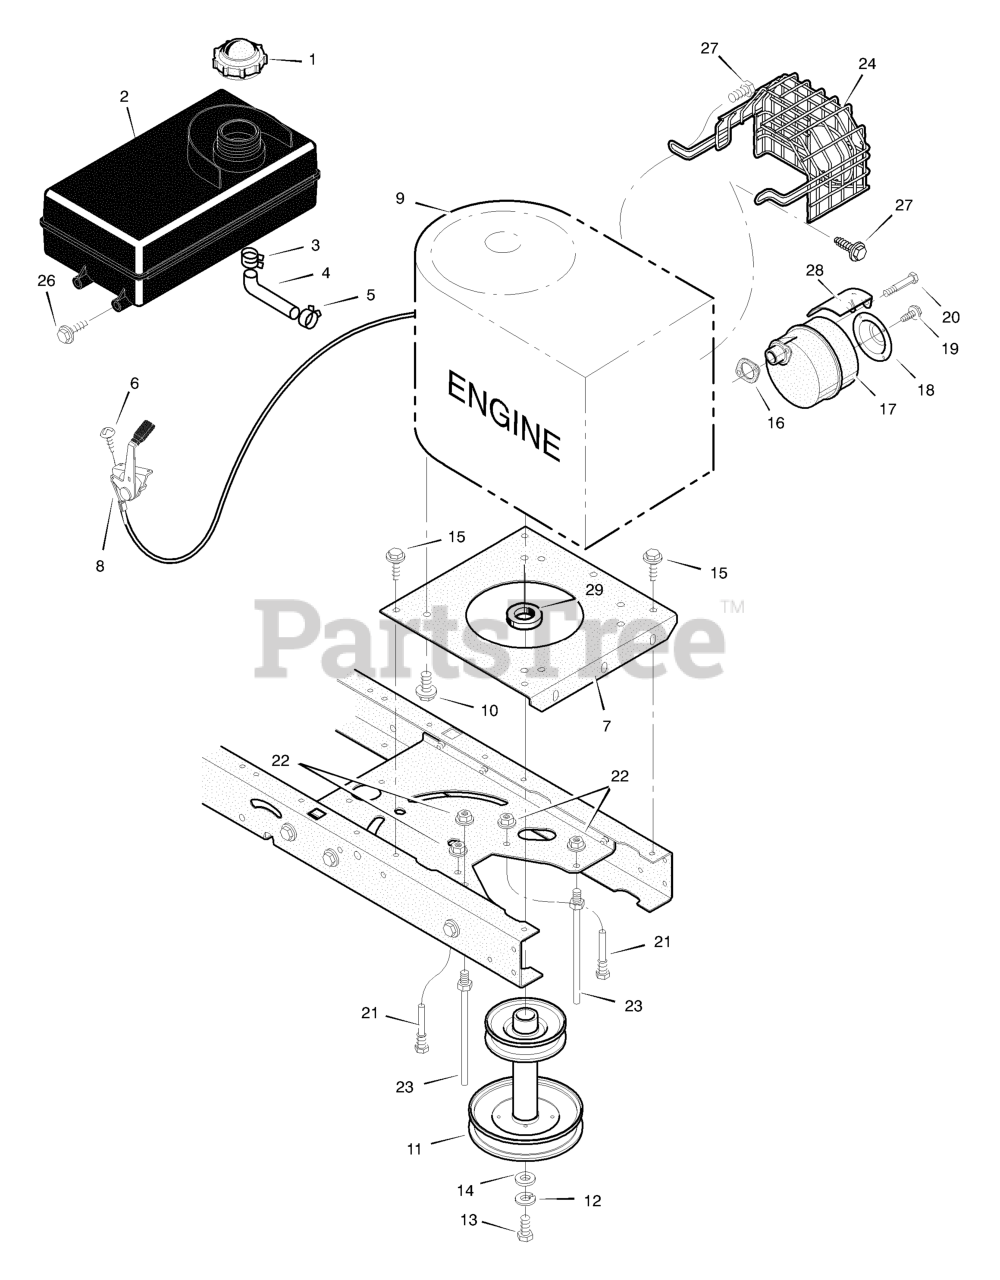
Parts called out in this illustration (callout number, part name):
1	Fuel Cap
2	TANK, Fuel 1.4 Gal.
3	Hose Clamp
4	Fuel Line (Must cut to length)
5	Hose Clamp
7	Plate, Engine
8	Throttle Control
9	Engine, Briggs & Stratton *
10	Bolt, Engine Mount
11	STACK PULLEY ASSEMBLY
12	Lockwasher
13	Bolt, Hex
16	GASKET, Exhaust
17	Muffler
18	Deflector, Muffler
20	Bolt, Hex
21	Guide, Belt
22	Nut, Flange
23	Guide, Belt
24	Shield, Heat
28	Shield, Heat
29	Spacer, Engine
